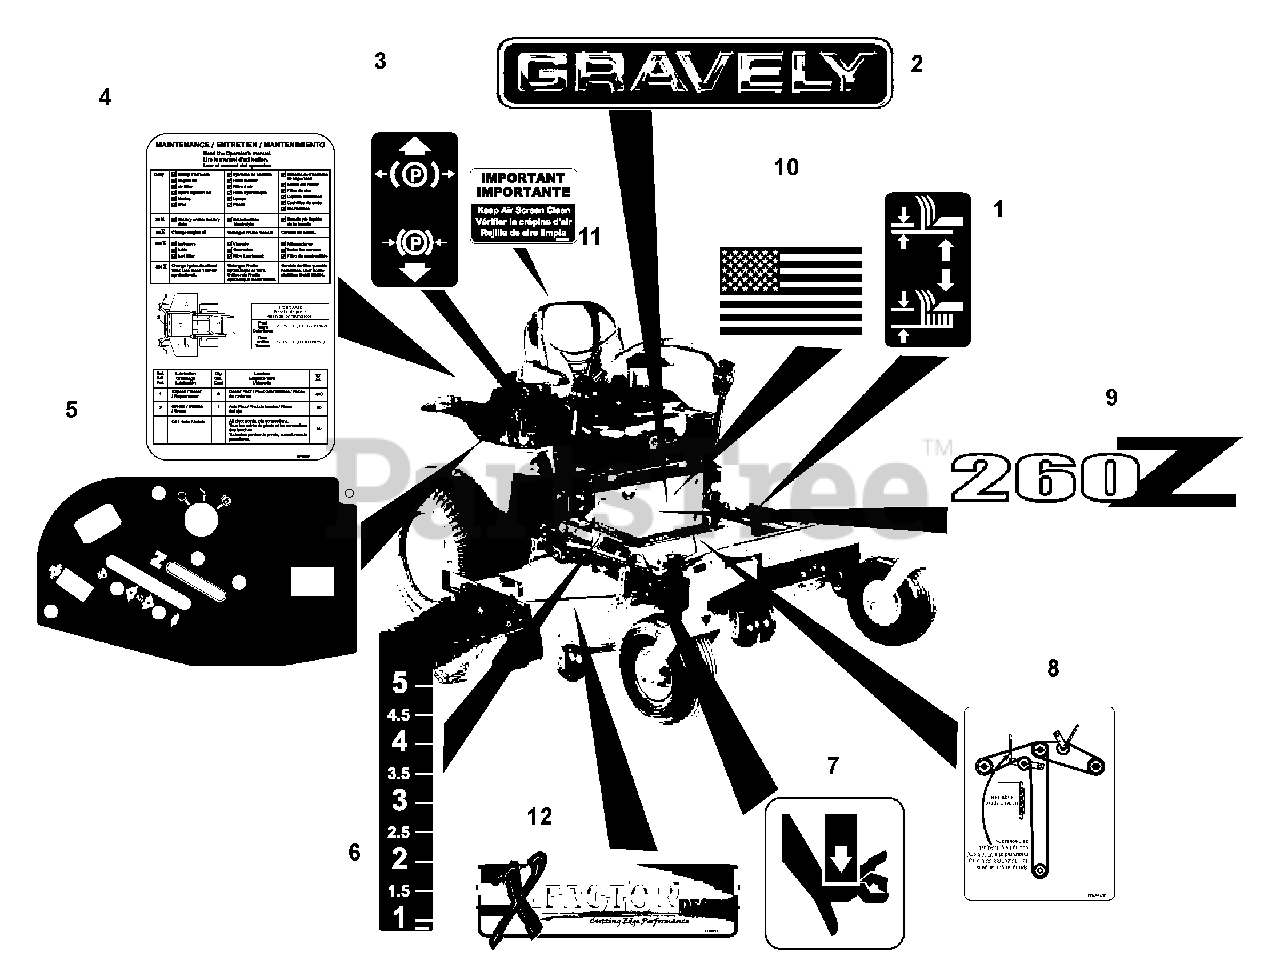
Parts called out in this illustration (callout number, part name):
1	Decal, Lift Lever
2	Decal, 15 in. Gravely Logo
3	Decal, Parking Brake Lever
4	Decal, Service Instructions
5	Decal, Control Panel
6	Decal, Height of Cut
7	Decal, Pinch Point
8	Decal, Belt Diagram
9	Decal, PM-260Z
9	Decal, PM-272Z
9	Decal, PM-252Z
10	Decal, American Flag
11	Decal, Warning Clean Debris
12	Decal, X-Factor Deck
